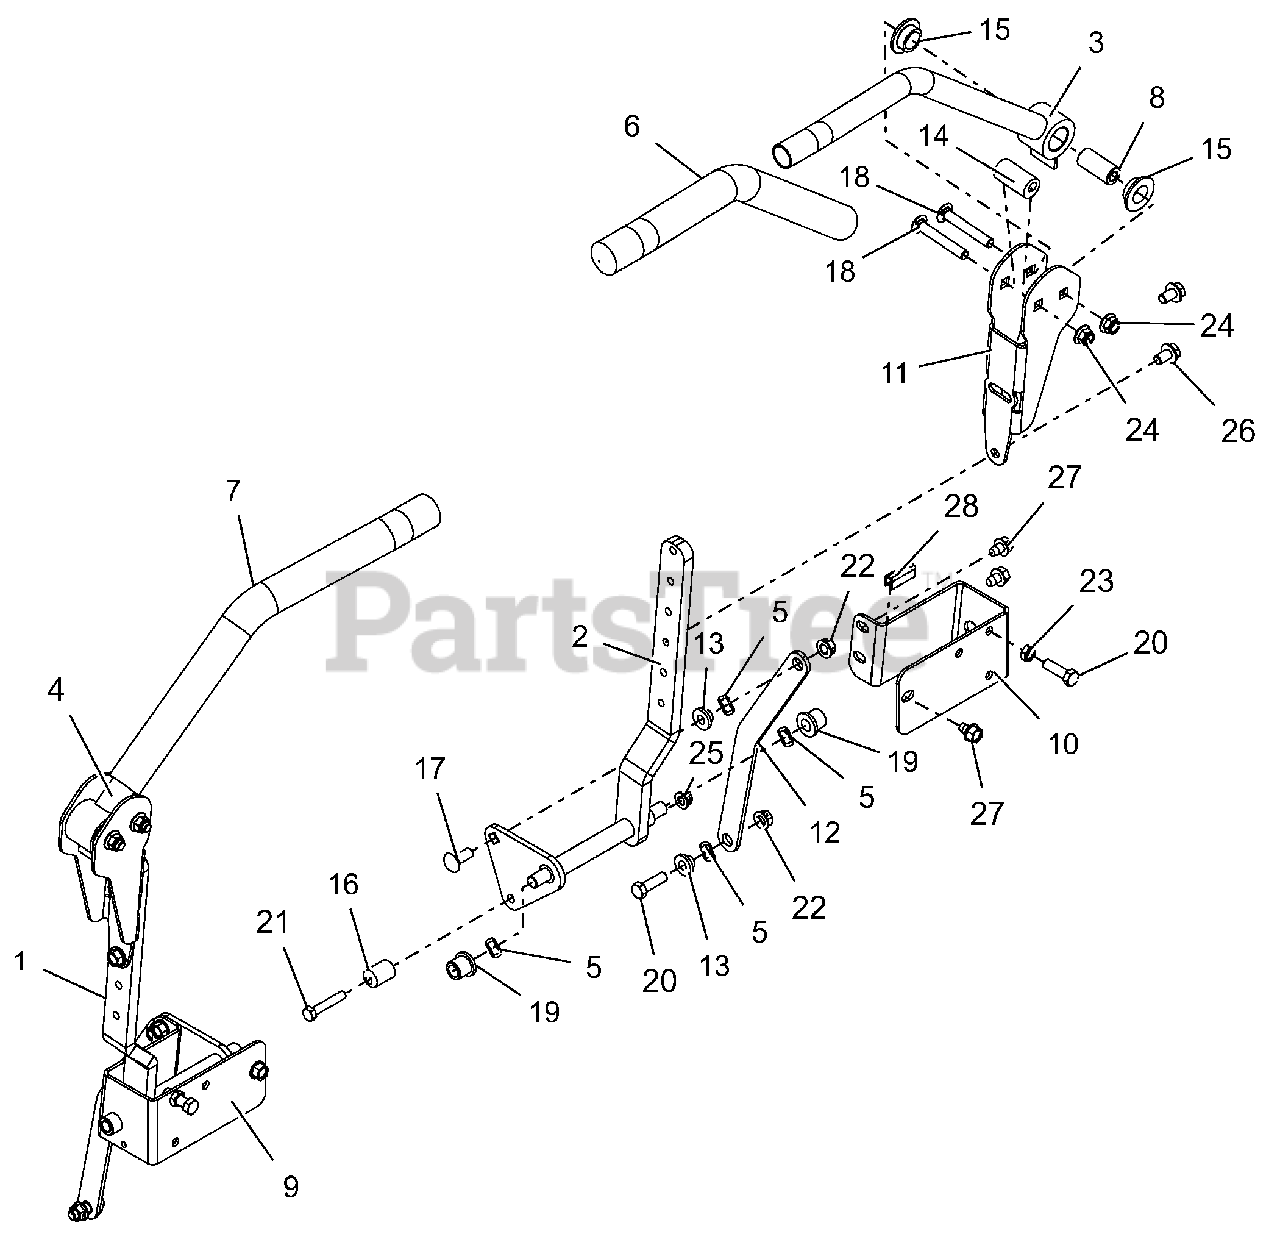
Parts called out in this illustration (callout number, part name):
1	WMT,PT/PT100RH LOWER CNTRL ARM
2	WMT,PT/PT100LH LOWER CNTRL ARM
3	WLDMT, CONTROL HANDLE- BLK
4	WLDMT, CONTROL HANDLE- BLK
5	WAVE WASHER .531X.781X.125FH
6	GRIP, HANDLEBAR
7	GRIP, HANDLEBAR
8	SPACER, STEERING ARM
9	RH PT/PT100 DRV CNTRL STOP-RED
10	LH PT/PT100 DRV CNTRL STOP-RED
11	ADJ UPPER CONTROL ARM BRKT-BLK
12	LINK, DRIVE CONTROL - BLACK
13	BSHG-FLG .385X.500X.875X.406
14	BSHG, ECCENTRIC.406X.875X1.625
15	BSHG-FLG .762X1.48X.44 NYL
16	ECCENTRIC
17	@BLT-RDHDSQNK .38-16X1.00 G5YZ
18	BLT-RDHDSQSHK, 38-16X2.50 G5YZ
19	BHSG-FLG .500X.750X.750X.125
20	@BLT-HEX .38-16X1.25 GR5 YWZC
21	@BLT-HEX .31-18X1.75 GR5 YWZC
22	NUT-LK-CTR-FLG .38-16 YWZC
23	NUT-HEX-JAM .375-16 YWZC
24	@NUT-LK-NYL-FLG .38-16 YWZC
25	@NUT-LK-NYL-FLG .31-18 YWZC
26	BLT, SCRHFWH .375-16X.625 YWZC
27	@SCR-TAP .38-16X.50 HWH TR YWZ
28	STRIP, COWL
